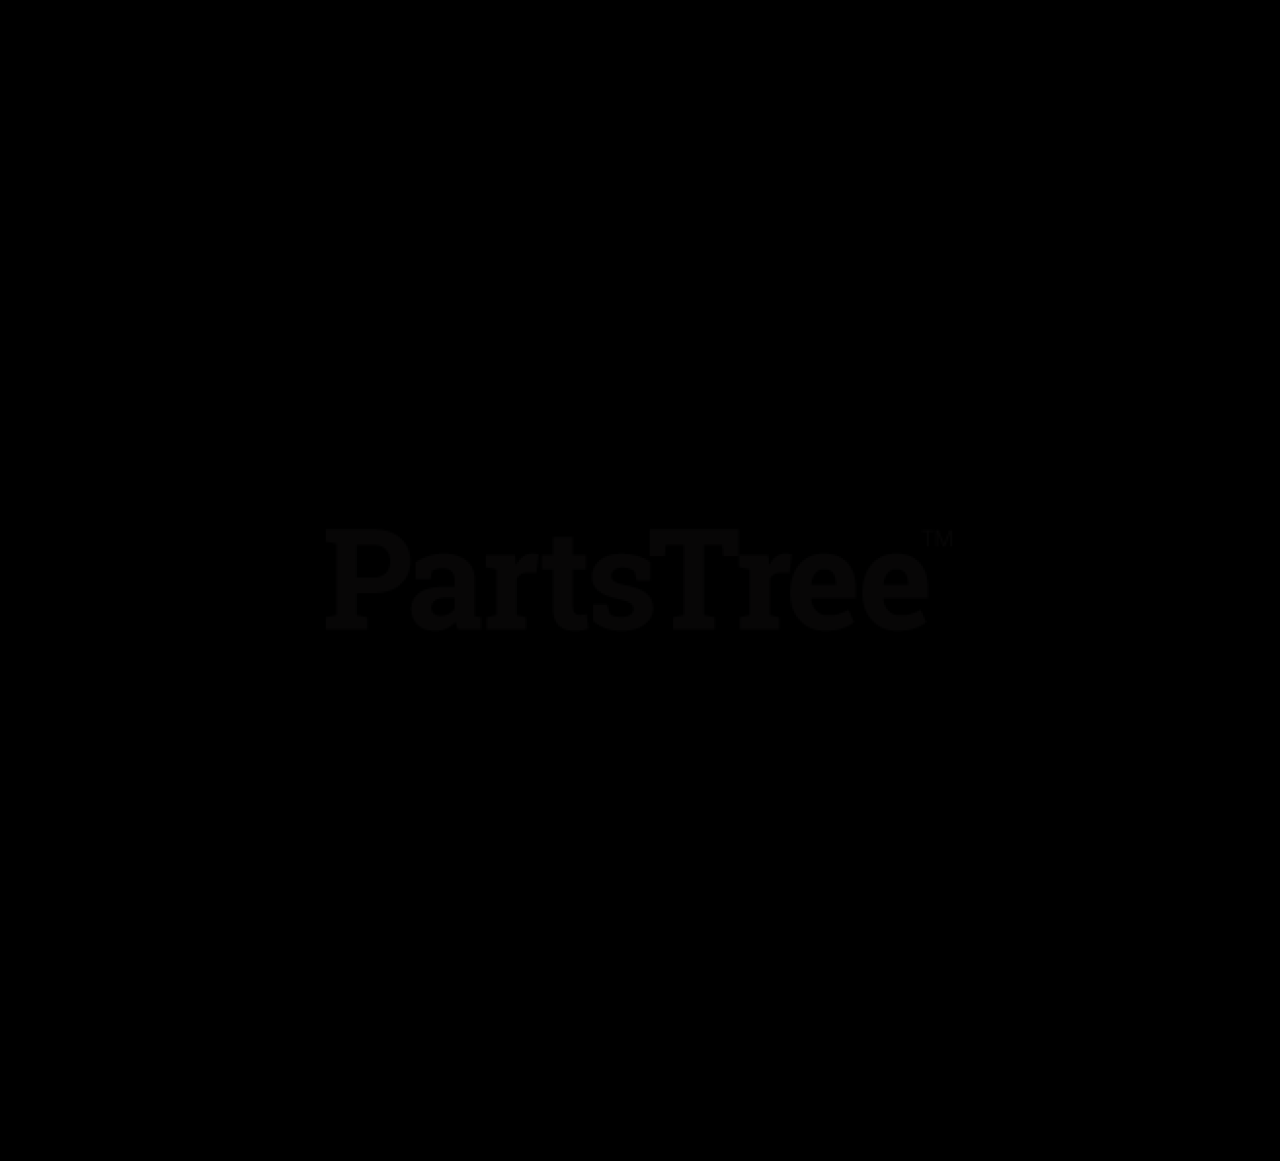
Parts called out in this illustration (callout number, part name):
1	Bolt, Hex .875-9 x 2.75 Grade 5
2	Mower Mounting Arm Weldment
3	Nut, Locking Center .875-9
4	Bearing, .75 x .875 x 1.00
5	Bolt, Hex .38-16 x 1.00 Grade 5
6	Weldment, Mower Mounting Pin
7	Bolt, Hex M12-1.75 x 50 Grade 5
8	Chain, Link
9	Cap, Vinyl .50ID x 1.50LG x .055
10	Nut, Spin Lock Flange M12-1.75
11	Bumper, Rubber
12	Coupling Nut, .31-18 x 3.00
13	Nut, .38-16 Nyloc Flange
14	Assembly, Mower Mounting Arm (Includes item # 2 and item # 4)
15	Bracket, Deck Leveling
16	Nut, Jam .312-18
17	Bolt, Hex .31-18 x 2.00 Full Thread
18	Screw, Tapping .38-16 x .50 Hex Washer Head Thread (215)
19	Bolt, Hex .312-18 x 1.50 Grade 5
20	Bolt, Round Head Square Neck .31-18 x .75 Loc-Tite
